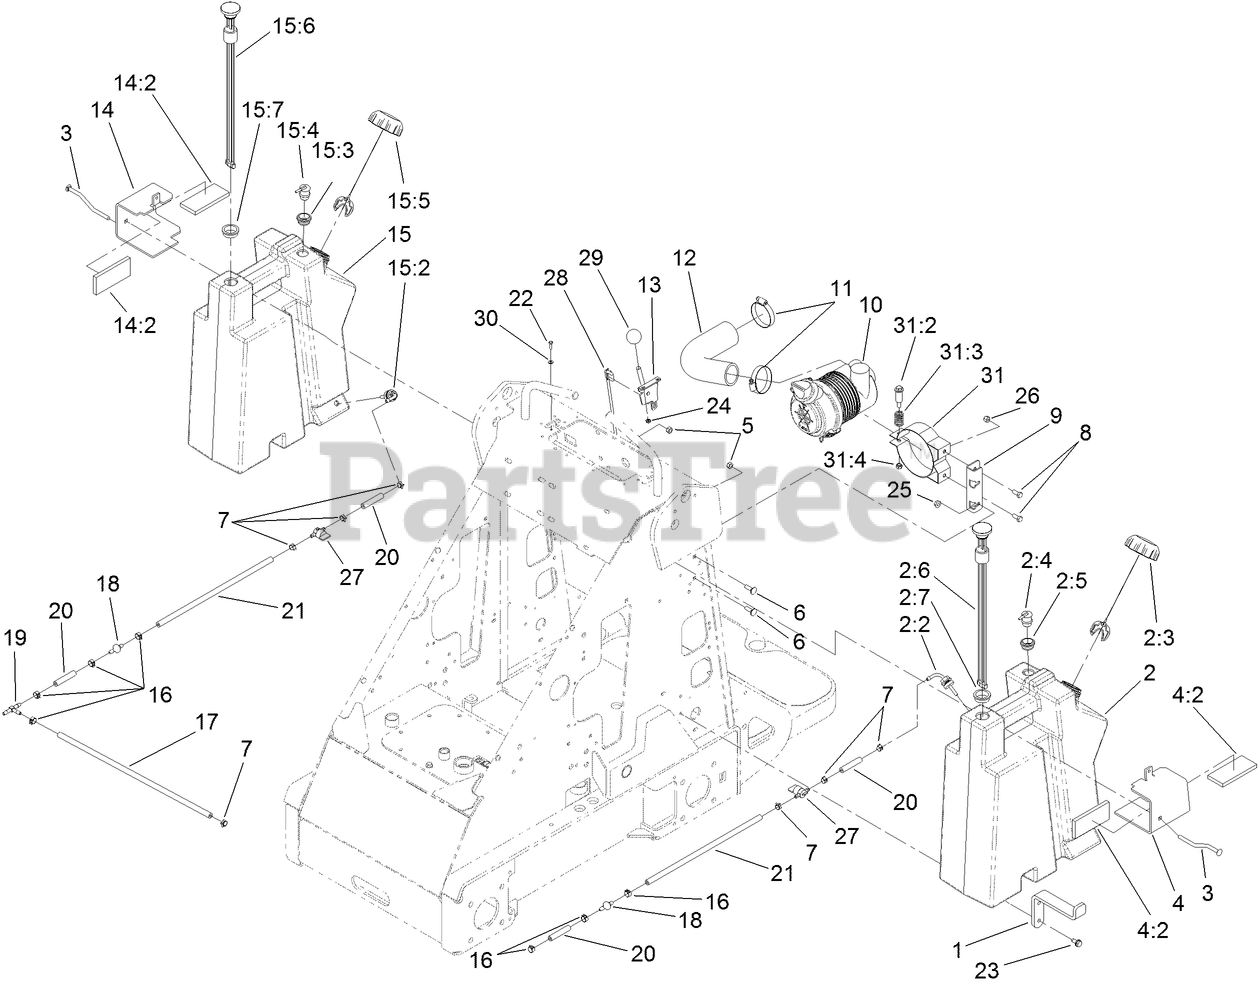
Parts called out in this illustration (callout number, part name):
1	MOUNT-TANK, BOTTOM
2	LH FUEL TANK ASM
2:2	FITTING-FUEL, BULKHEAD
2:3	CAP-FUEL
2:4	VALVE-ROLLOVER
2:5	GROMMET
2:6	GAUGE-LEVEL, FUEL
2:7	GROMMET
3	BOLT-MOUNT
4	LH TANK MOUNT ASM
4:2	PAD-FOAM
5	NUT-HEX, SIDE DEFORM
6	BOLT-CARR
7	CLAMP-HOSE
8	SCREW-HH
9	MOUNT-CLEANER, AIR
10	AIR CLEANER ASM
11	CLAMP-HOSE
12	HOSE-AIR
13	LEVER-CONTROL
14	RH TANK MOUNT ASM
14:2	PAD-FOAM
15	RH FUEL TANK ASM
15:2	FITTING-FUEL, BULKHEAD
15:3	CAP-FUEL
15:4	VALVE-ROLLOVER
15:5	GROMMET
15:6	GAUGE-LEVEL, FUEL
15:7	GROMMET
16	CLAMP-HOSE
17	HOSE-FUEL
18	VALVE-CHECK, FUEL
19	FITTING-TEE, BARBED
20	HOSE-FUEL
21	HOSE-FUEL
23	SCREW-HWHTF
24	NUT-KEPS
25	NUT-HF
26	NUT-LOCK, NI
27	VALVE-FUEL
28	CABLE-CONTROL
30	WASHER-FLAT
31	AIR CLEANER MOUNTING BAND ASM
31:3	SPRING
31:4	NUT
